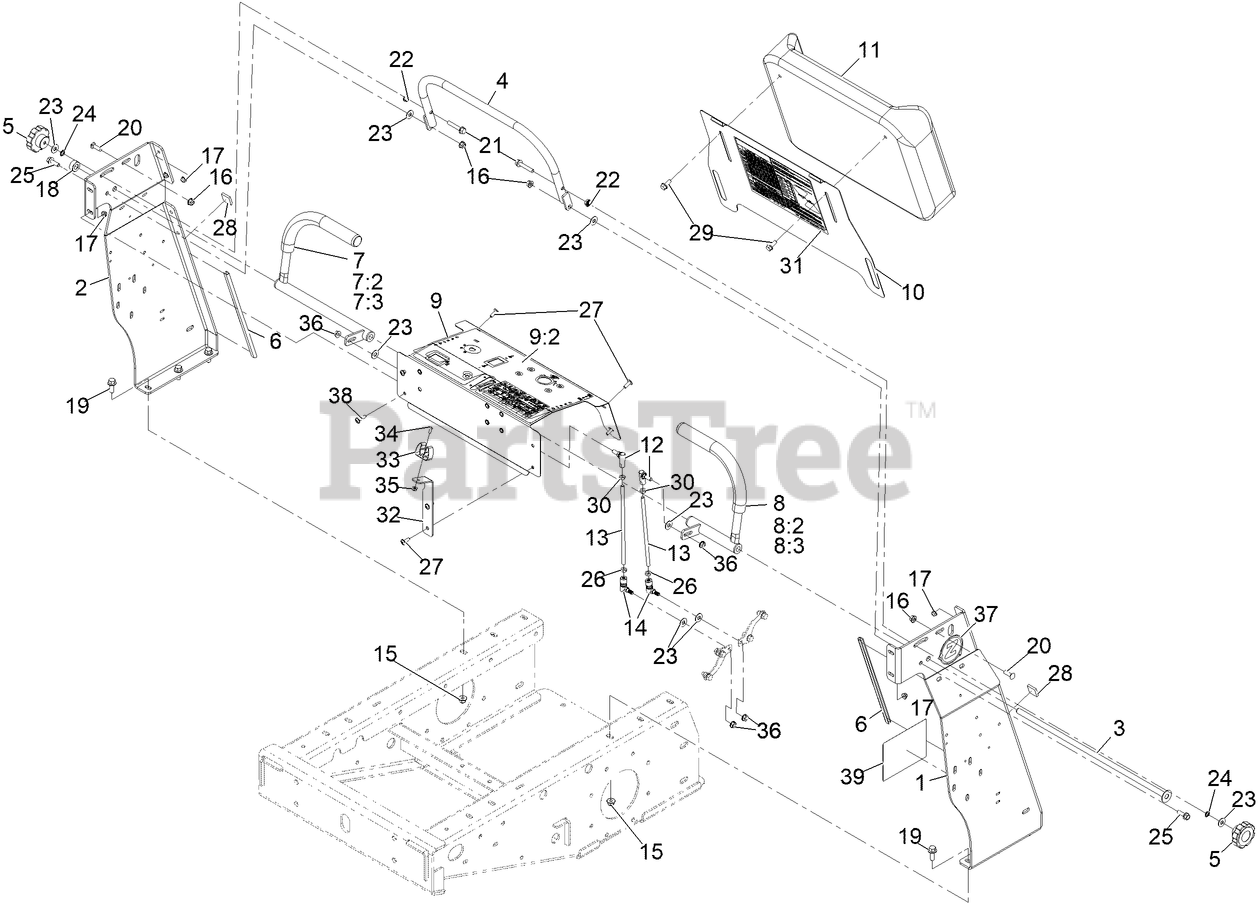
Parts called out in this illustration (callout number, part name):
1	Upright-Tower, Lt [blk-Txt]
2	Upright-Tower, Rt [blk-Txt]
3	Rod-Pivot, Joy Stick
4	Bar-Speed [blk-Txt]
5	KNOB-FLUTED
6	STRIP-TRIM, 12.0"
7	Stick-Joy, Rt
7:2	GRIP-CONTROL, MOTION
7:3	Bushing,Flange,0.50 ID,0.75 OD
8	Stick-Joy, Lt
8:2	GRIP-CONTROL, MOTION
8:3	Bushing,Flange,0.50 ID,0.75 OD
9	ASM-PANEL, CONTROL
9:2	Decal-Control Panel
10	PLATE-PAD, KNEE
11	PAD-KNEE, Z-LOGO
12	Balljoint-SS
13	ROD-CONTROL, MOTION
14	Ball Joint-Quick Disconnect, SS
15	Nut-Hex Flange
16	Nut-Hex Flange
17	Nut-Hex Flange
19	SCREW-HHF
20	Bolt,Carriage,5/16-18X1,ST/ST 18-8
21	Screw-HHF
22	Nut,Hex Flange,5/16-18,Sst, Rie2006
23	FLAT WASHER, 5/16 NOM,ST
24	Washer-Lock
25	SCREW-HHF
26	Nut-Hex
27	Screw-Hsbhf
29	SCREW-HHF
30	Nut-Hex
31	DECAL-SPRAY CHART
32	Mount-Gun
33	Holder-Tool, Clip
34	Screw-HSBH
35	Nut-Hex Flange
36	Nut-HHF
37	Decal-Z-Logo
38	Screw-Hsbhf
39	Decal-Service Aid
